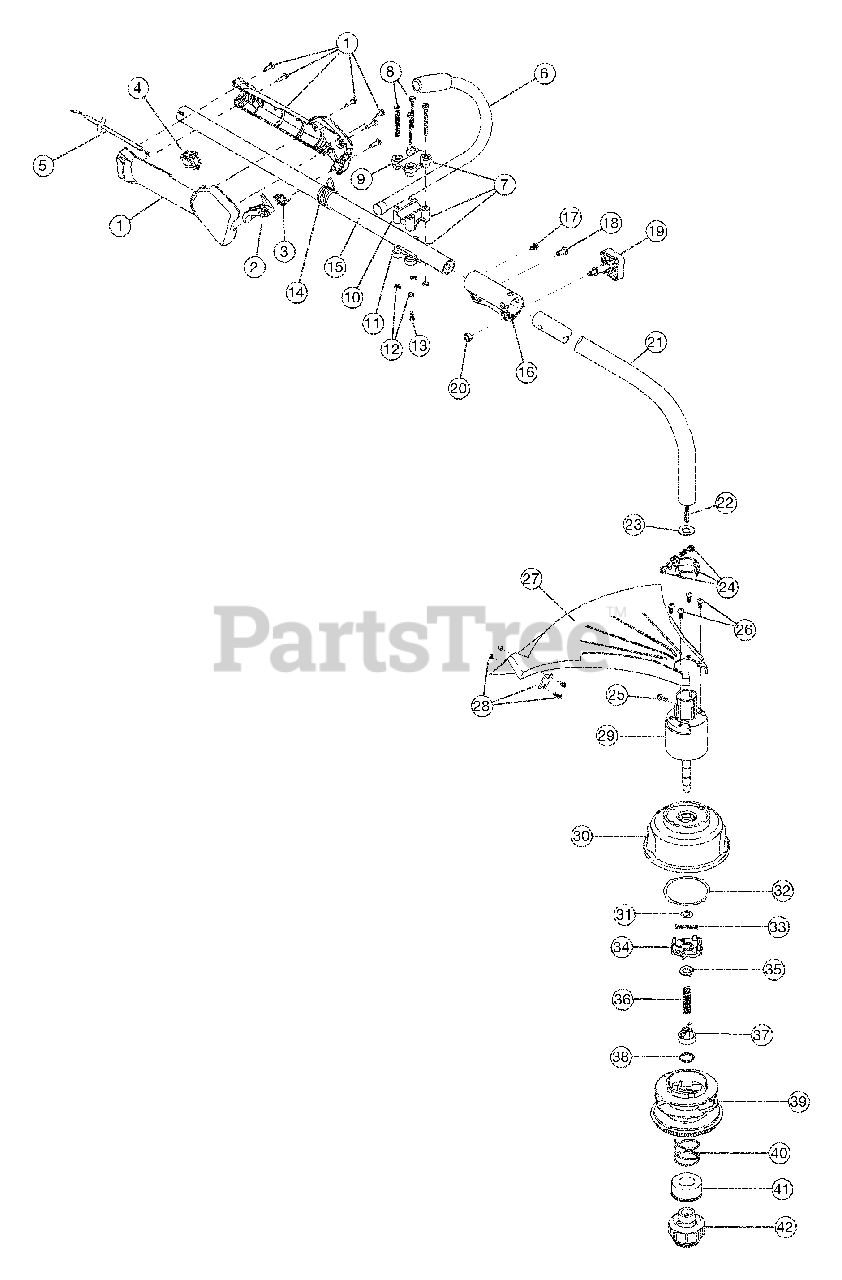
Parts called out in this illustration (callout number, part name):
1	Throttle Housing and Trigger Assembly
2	Throttle Trigger
3	Throttle Trigger Spring
4	Switch Assembly
5	Throttle Cable
6	J-Handle Assembly
7	Handle Bracket Assembly
9	Upper Handle Clamp
10	Middle Handle Clamp
11	Lower Handle Clamp
13	Anti-Rotation Screw
14	Harness Clip
15	Upper Drive Shaft Housing Assembly
16	EZ-Link(TM) Coupler
19	Adjustment Knob
20	Knob Retaining Nut
21	Lower Drive Shaft Housing Assembly
22	Lower Flexible Drive Shaft
23	Palnut
24	Lower Clamp Assembly
25	Anti-Rotation Screw
26	Shield Mounting Hardware
27	Shield and Blade Assembly
28	Blade Assembly
29	Bushing Housing Assembly
30	Outer Spool Assembly
31	Retaining Ring
32	Thrust Washer
33	Small Spring
39	Inner Reel
40	Large Spring
42	Bump Head Knob Assembly
